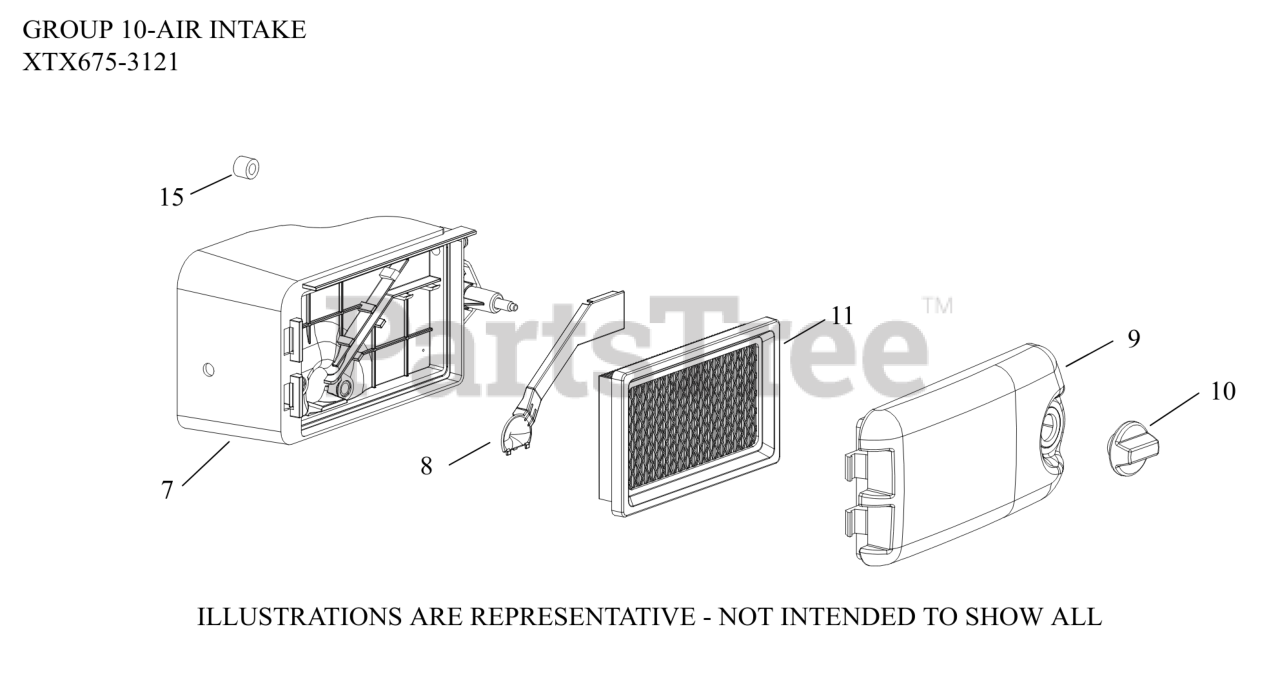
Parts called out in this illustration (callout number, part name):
7	AIR CLEANER BASE-USE 14 094 23-S
8	COVER, A/C BASE (BREATHER GAS)
9	COVER, AIR CLEANER
10	KNOB-USE 14 341 07-S
11	ELEMENT, AIR FILTER
15	SPACER, AIR CLEANER BASE
